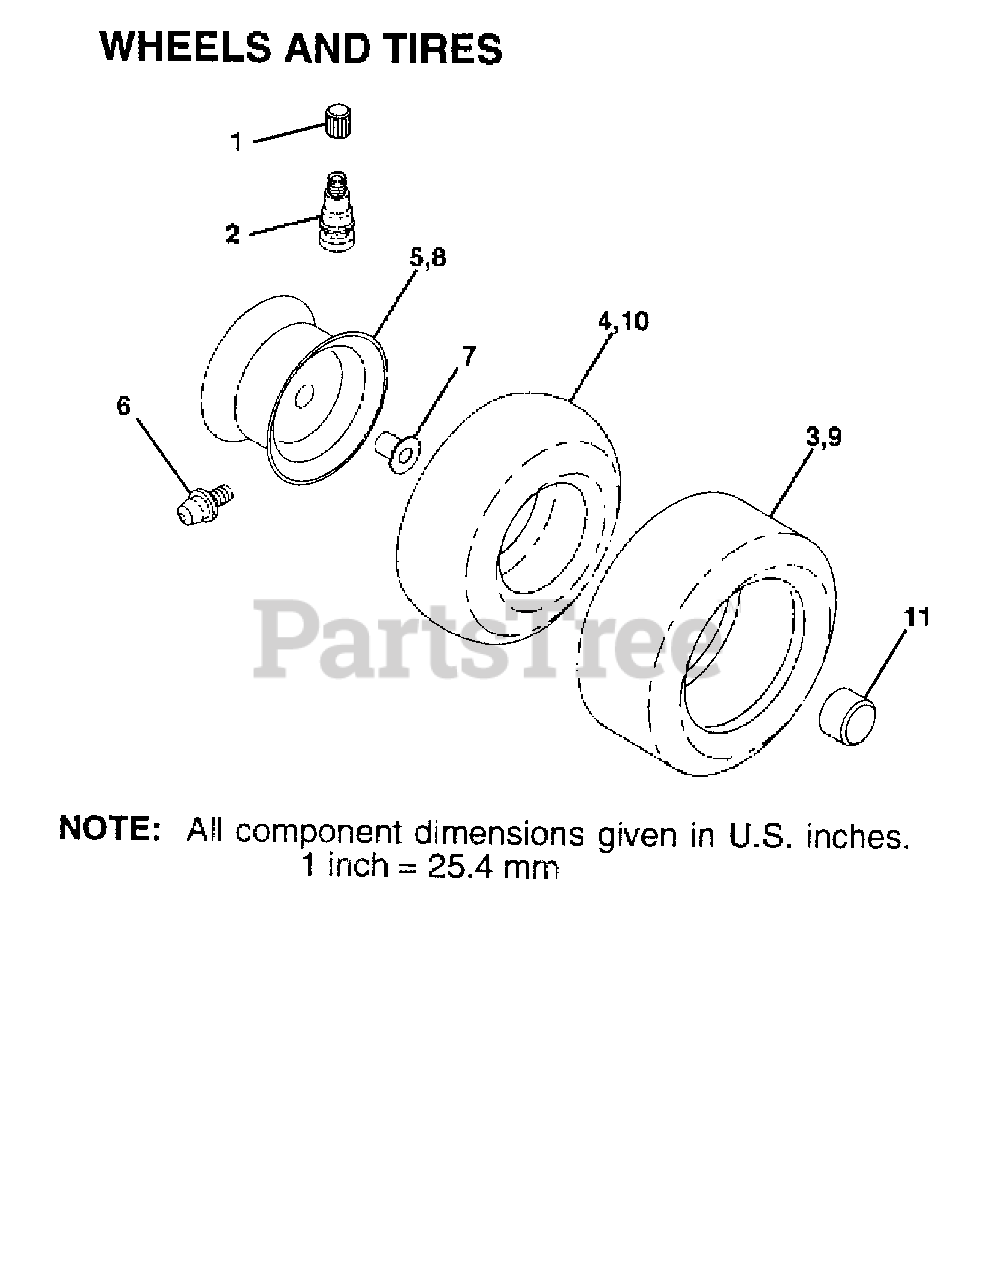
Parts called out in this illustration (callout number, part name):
1	VALVE CAP
2	VALVE STEM LT
3	TIRE HEAVY DUTY
4	TUBE.5.3/4.5/6
5	Rim Assembly, 8 X 5 Front Silver
6	FITTING LT
7	BEARING T
8	RIM.ASM.12"REAR.SILVER
9	Tire, .23 X 8.5-12 Turf Saver
10	TUBE.23"X9.5""X12""
11	CAP.HUB.FRONT.LT.BLACK
